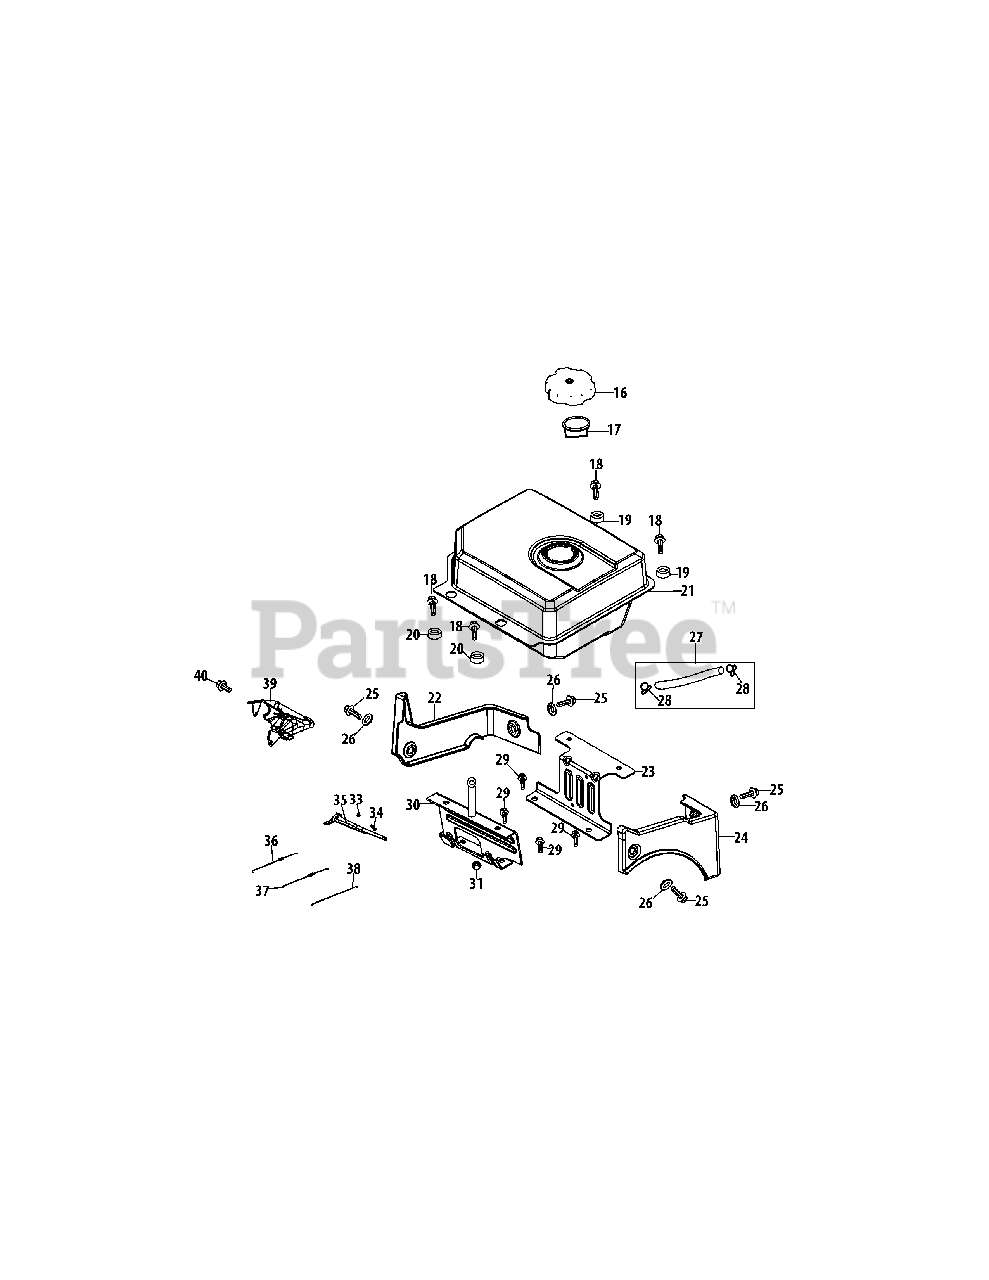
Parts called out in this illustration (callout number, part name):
16	Fuel Cap Assembly
17	Fuel Level Indicator
18	Bolt M8×20
19	Bush I, Gas Tank
20	Bush II, Gas Tank
21	Fuel Tank Assembly
22	Left Trim Plate
23	Rear Mainting Bracket Assy.
24	Right Trim Plate
25	Bolt M6×16
27	Fuel Line Kit
28	Fuel Hose Clamp
29	Bolt M8×14
30	Gas Tank Support Bracket
33	Nut M6
34	Governor Arm Bolt
35	Governor Arm
36	Governor Spring
37	Throttle Linkage Spring
38	Throttle Linkage
39	Primer Bracket
40	Bolt M6×12
